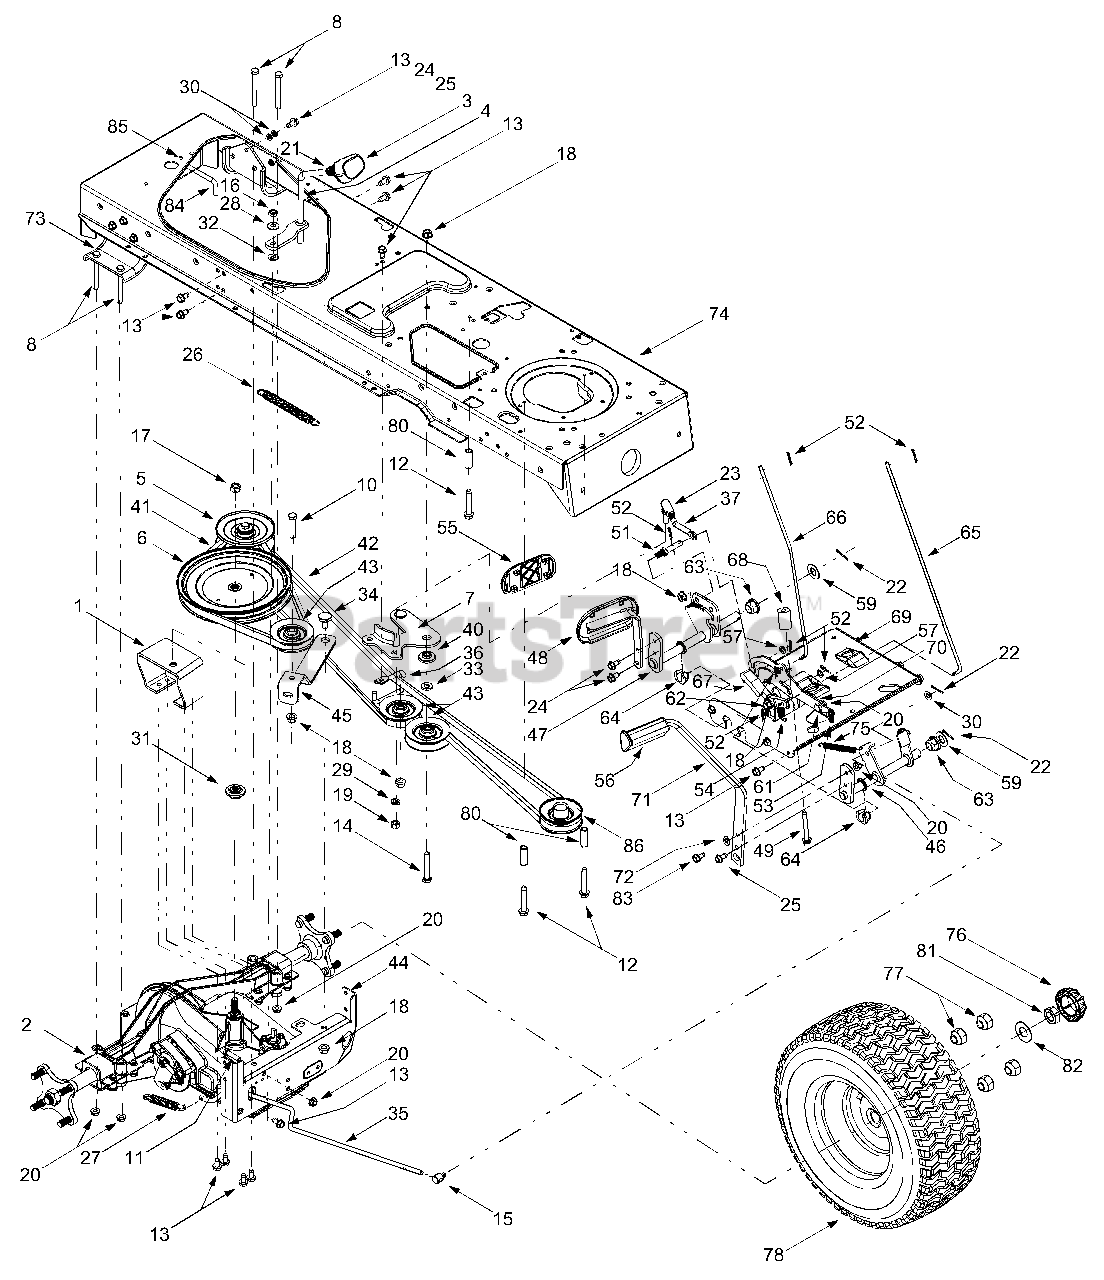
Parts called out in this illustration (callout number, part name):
1	Variable-speed Bracket Assembly
2	Two-speed Transmission Assembly
3	Shifter Knob
4	Shift Lever
5	Variable-speed Pulley Assembly
6	Transmission Pulley, 8.5
7	Double-idler Bracket
8	Hex Cap Screw, 5/16-18 x 2.75
10	Hex Cap Screw, 3/8-16 x 1.75
11	Hex Cap Screw, 5/16-18 x 1.5
12	Self-tapping Screw, 1/4-20 x 1.25
13	Self Tapping Screw, 5/16-12 x.75
14	Hex Cap Screw, 3/8-16 x 2.25
15	Ferrule, 5/16 x.312 Dia.
16	Hex Jam Nut, 3/8-16
17	Hex Flange Nut, 7/16-20
18	Flange Lock Nut, 3/8-16
19	Hex Nut, 3/8-16
20	Flange Lock Nut, 5/16-18
21	Hex Jam Nut, 3/8-16
22	Cotter Pin
23	Ball Joint, 3/8-24
24	LD Screw, 5/16-18 x.75
25	Self-tapping Screw, 5/16-18 x.875
26	Extension Spring,.62 Dia. x 6.12
27	Extension Spring,.59 OD x 4.0
28	Bell Washer,.401 x.870 x.063
29	Lock Washer, 3/8
30	Flat Washer, 5/16
31	Pulley Hub, 1/2 Spline
32	Flat Washer,.44 x.75 x.06
33	Flat Washer,.407 x.812 x.135
34	Shoulder Screw,.625 Dia. x.21
35	Brake Rod
36	Belt Guard
37	Idler Adjustment Rod, 3/8
40	Shoulder Spacer,.380 ID
41	Variable-speed Belt
42	Drive Belt
43	Flat Idler, 2.75 OD
48	Drive Pedal Assembly
49	Self Tapping Screw, 5/16-18 x 2.5
51	Pin, 3/8-16 x 2.43
52	Cotter Pin
53	Compression Spring,.405 x 1.17
54	Extension Spring,.5 OD x 1.41
55	Drive Pedal Pad
56	Brake Pedal Pad
57	Flat Washer,.385ID x.870OD
59	Flat Washer,.64 x 1.24 x.06
61	Shoulder Screw,.437 x 1.62
62	Shoulder Screw,.5 x.434
63	Hex Flange Bearing
64	Split Hex Flange Bearing
65	Cruise Control Rod
66	Brake Lock Control Rod
67	Cruise Latch
68	Spacer, 5/16 x 1.54
70	Drive Lockout Bracket
76	Hub Cap
77	Lug Nut, 7/16-14
80	Spacer,.372 x.26 x 1.03
81	Jam Nut, 3/4-16
82	Flat Washer,.78 x 1.59 x.06
83	Self-tapping Screw, 5/16-18 x.75
84	Transmission Belt Guard Rod
85	Self Tapping Screw,1/4-20 x.5
86	Engine Pulley, 3.56"
